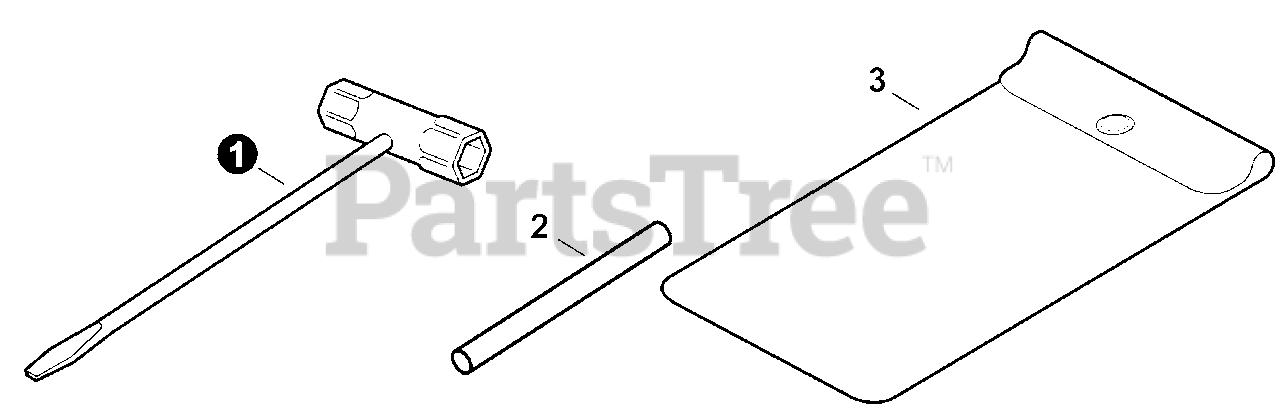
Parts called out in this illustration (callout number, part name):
1	T-WRENCH 17x-19 L200
2	TOOL, LOCKING 5×120 MM
3	BAG, TOOL
